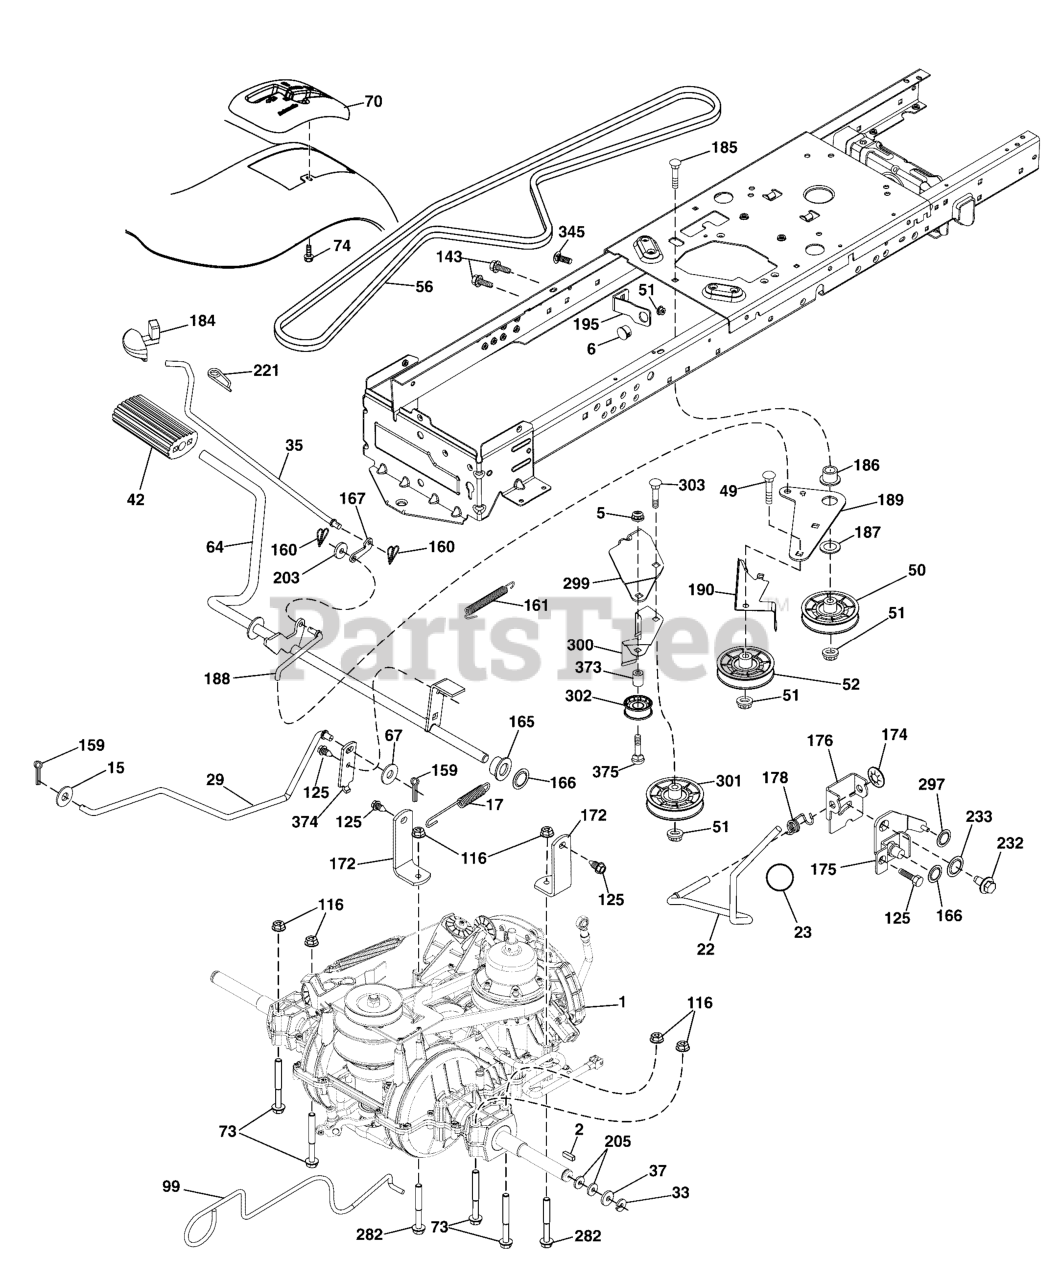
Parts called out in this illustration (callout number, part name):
1	TRANSAXLE, Gentrans Variator
2	KEY, Square, 2.0 x .1845/.1865
5	NUT, Crownlock
6	BUSHING, Snap
15	WASHER, 13/32 x 13/16 x 16 Ga.
17	SPRING, Brake
22	ROD, Shift
23	KNOB
29	ROD, Brake
33	E-RING, #5133-75
35	ROD, Brake Parking Lt. Tex
37	WASHER, .793 x 1.637 x 060
42	COVER, Pedal Black Round
49	BOLT, 3/8-16 UNC x 1-3/4 Gr 5
50	IDLER, Flat
51	NUT, Hex Flangelock, 3/8-16
52	IDLER, V-Groove
56	BELT, Drive, 100.97"
64	SHAFT, Assembly Pedal Brake Control
67	WASHER, 13/32 x 13/16 x 12 Ga.
70	CONSOLE
73	BOLT, Hex Flange Head, 5/16-18 Gr 5
74	SCREW, Hex Washer 1/4 X 1/2 UNC
99	ROD, Bypass
116	NUT, Lock Hex Flange, 5/16-18
125	SCREW, 5/16-18 x 3/4
143	SCREW, Thread Rolling, 5/16-18 x 1/2
159	PIN, Cotter 1/8 x 3/4
160	CLIP, Retainer, Dia. 290
161	SPRING, Return Clutch, 6.75
165	BUSHING, Shaft Brake Hand
166	NUT, Push, .625
167	LATCH, Brake Parking
172	STRAP, Torque Lh/Rh
174	NUT, Push, .500
175	SHAFT, Assembly Shift
176	ARM, Clevis Rod Shift
178	SPRING, Shift Gt 2006
184	HANDLE, Parking Brake, .505
185	BOLT, 3/8-16 UNC x 2-3/4 Gr 5
186	SPACER, Retainer
187	WASHER, 13/32 x 2 x 10 Ga.
188	LINK, Clutch Ground Drive
189	BELLCRANK, Groundrive Nesting
190	KEEPER, Bellcrank Drive Ground
195	BRACKET, Brake
203	WASHER, 11/32 x 11/16 x 16 Ga.
205	WASHER, 25/32 x 1-5/8 x 16 Ga.
221	RETAINER, Spring Clip Handle
232	BOLT, Fin Hex, 7/16-14 x 1 Gr 5
233	WASHER, Serrated
282	SCREW, Thread Rolling, 5/16-18 x 3
297	NUT, Push, 1/4
299	BRACKET, Mount Idler
300	KEEPER, Idler Rear
301	PULLEY, Idler V-Groove
302	PULLEY, Idler Flat, 2.0 Od
303	BOLT, Round Head Square Neck, 3/8-16 x 2-1/4
345	BOLT, Round Head Square Neck, 3/-16 x 1 Gr 5
373	SPACER, Idler
374	ARM, Control Brake
375	BOLT, Hex
